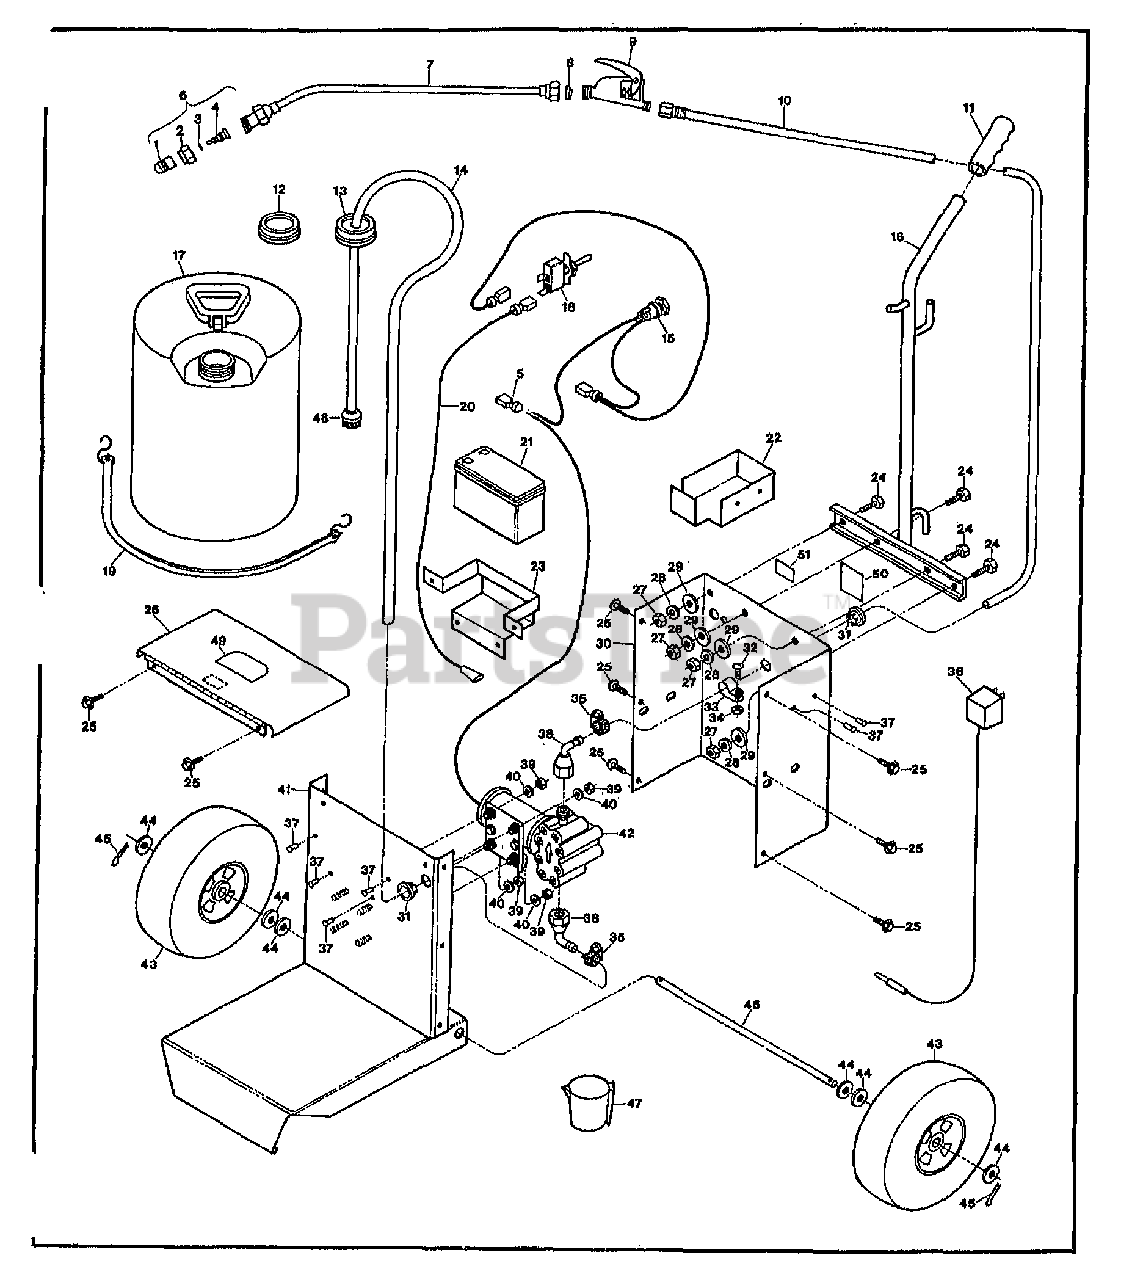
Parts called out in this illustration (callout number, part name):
1	TIP-BRASS BODY #5457 10835
2	ASSM-ADJ CONE W5500
3	RING-O 5500 CONE JET
4	ASSM-ADJ CONE W5500
5	TERMINAL
6	ASSM-ADJ CONE W5500
7	EXTENSION-SPRAY 10825
8	WASHER-TEFLON/BRASS 10842
9	VALVE-SHUT OFF PISTOL 10824
10	HOSE W/FITTINGS 10845
11	GRIPS-HANDLEBAR
12	CAP-E/S TANK 10868
13	CAP W/HOLE 10869
14	HOSE-1/4" X 4' 10841
15	KIT-CHARGING 10871
16	ASSM-HANDLE
17	TANK-REPL
18	SWITCH-TOGGLE 10830
19	STRAP-RUBBER 10826
20	WIRE-ON/OFF-SWITCH PUMP
21	BATTERY-12V EL SPRAYER 10815
22	BRKT-ACCESSORY
23	ASSM-BATTERY BRKT
24	SCR-HH 5/16-18X1.0 G5 ZP
25	SCR-HW M10-24X.375 ZP
26	LID W/DECAL
27	NUT-HEX 5/16-18 ZP
28	WASHER-LK .312 ZP
29	WASHER-1.25X.375X.1 ZP
30	HSG-CHASSIS W/DECALS
31	BUSHING-SNP 10827
32	SCR-RH M10-32X.5 MACH
33	CLAMP-CABLE 10828
34	NUT-HH M10-32X.125
35	CLAMP-HOSE 10829
36	CHARGER-BATTERY EL SPRAYER
37	RIVET-POP 1/8-3/8 10840
38	SWIVEL-90 ELBOW 10843
39	NUT-HEX M10-24
40	WASHER-#10
41	ASSM-CHASSIS
42	PUMP-SHURFLO 11511 5GAL
43	ASSM-TIRE & WHEEL
44	WASHER-1.75X.625X.11
45	PIN-COTTER 3/32 X 1 1/4
46	AXLE-EL SPRAY 10847
47	CUP-MEASURING 8OZ 10833
48	STRAINER-EL SPRAYER 10832
49	DECAL-LOGO EL SPRAYER
50	DECAL-CHARGE 10817
51	DECAL-WARNING E/S 10818
